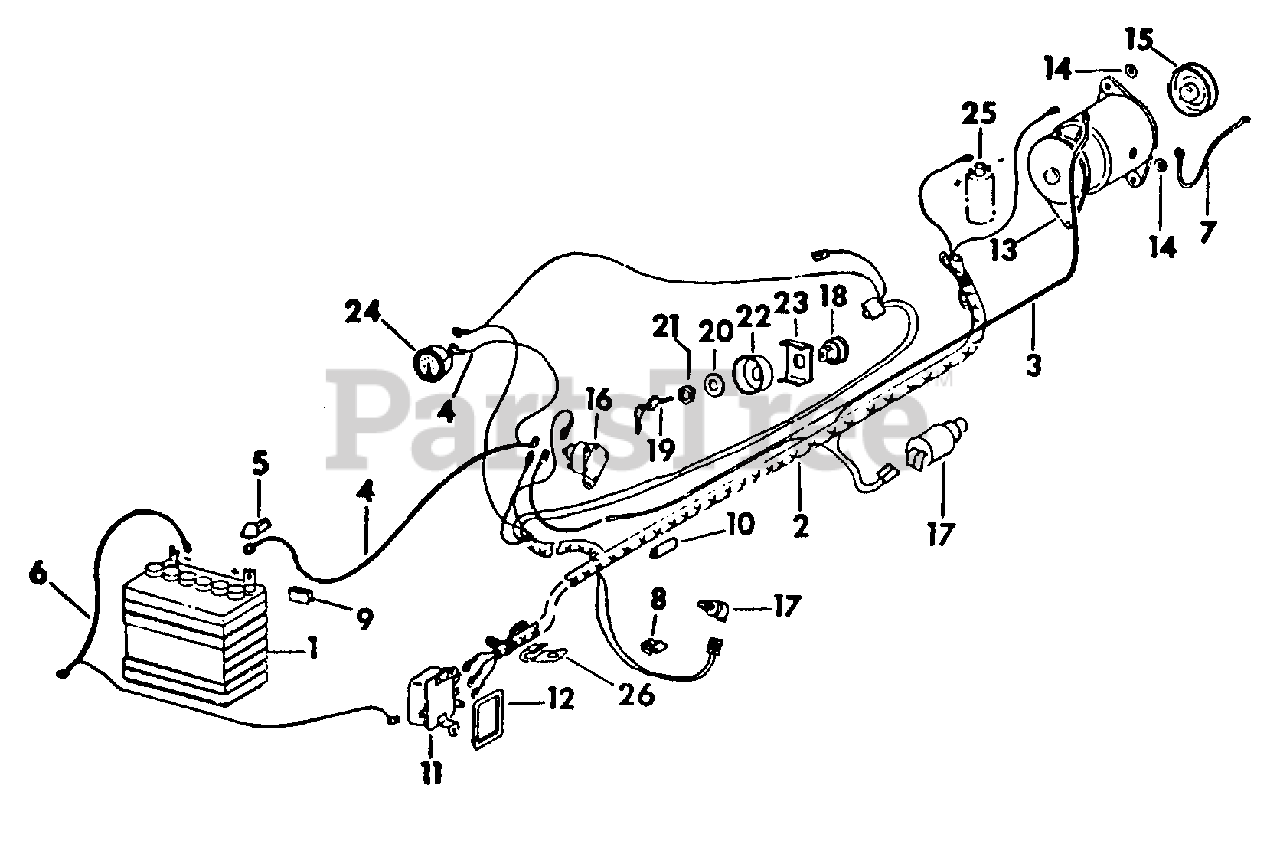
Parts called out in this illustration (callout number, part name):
1	Battery, IH Low Maintenance, 12 Volt
2	Cable Harness Rework Package
3	Cable, Magneto Switch to Generator A Terminal
4	Cable, Battery (Positive)
5	Cover, Battery Terminal
6	Cable, Battery Neg Terminal to Ground
7	Cable, Engine to Ground
8	Clip, Safety Starting Switch Cable
9	Grommet, Seat Support Edge
10	Grommet, Frame Edge
11	Regulator, Voltage
12	Gasket, Voltage Regulator
13	Starter Generator Assy
14	Shim, Starter-Generator Mtg Bolt, .005
15	Pulley, Starter-Generator Drive
16	Switch, Magnetic
17	Switch Assy, Neutral Starting
18	Switch w/Keys, Battery Ignition Key Start
19	Key, Ignition Switch
20	Washer, Battery Ignition Switch
21	Nut, Battery Ignition Switch
22	Socket, Ignition Switch
23	Retainer, Ignition Switch
24	Indicator, Charge
25	Coil
26	Clip, Right Front Fender Mtg Screw Cable
